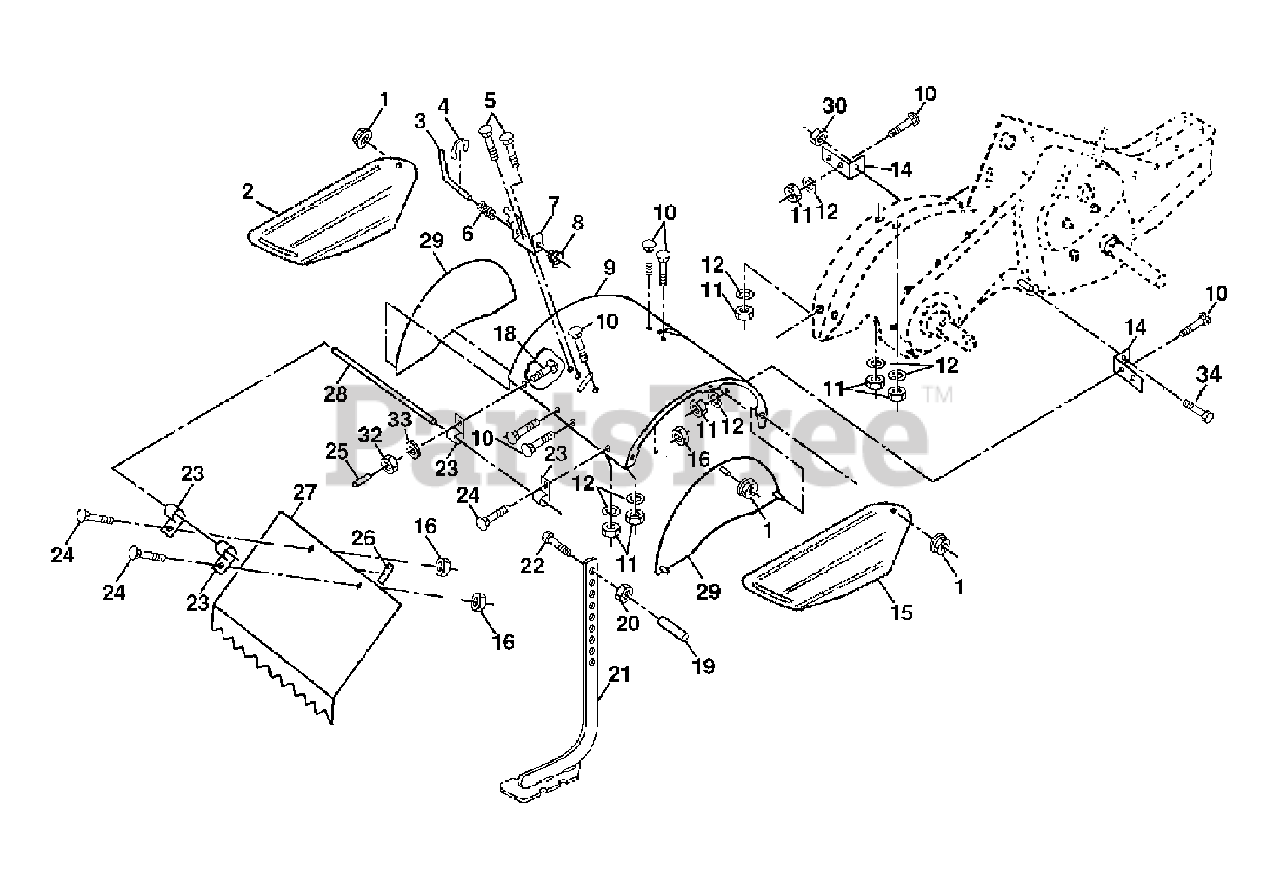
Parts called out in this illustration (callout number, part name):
1	Nut, Lock Hex Flange 5/16-18
2	Shield, Side, Outer L. H.
3	Pin, Stake, Depth
4	Ring, Klip
5	Bolt, Carriage 5/16-18 Unc x 1
6	Spring
7	Bracket, Latch
8	Spring, Depth Stake
10	Bolt Rdhd Sqnk 5/16-18 x 3/4 ZNC
11	Nut, Hex 5/16-18
12	Washer, Lock 5/16
14	Bracket, Shield Tine
15	Shield, Side, Outer R.H.
16	Nut, Flange Hex 1/4-20 UNC
18	Bolt, Carriage 1/4-20 x 1-1/4 r. 5
19	Grip
20	Nut, Hex 3/8-16
21	Stake, Depth
22	Bolt, Hex 3/8-16 x 2
23	Hinge
24	Bolt, Carriage 1/4-20 x 1/2 Gr.
25	Cap, Vinyl
26	Pad, Idler
27	Shield, Leveling
28	Pin, Hinge
30	Nut, Lock Hx Flange
32	Nut, Fin, Hex 1/4-20 UNC
33	Washer, Lock Hvy Helical 1/4
34	Bolt Hex Flghd 5/16-18 x 2-1/4
